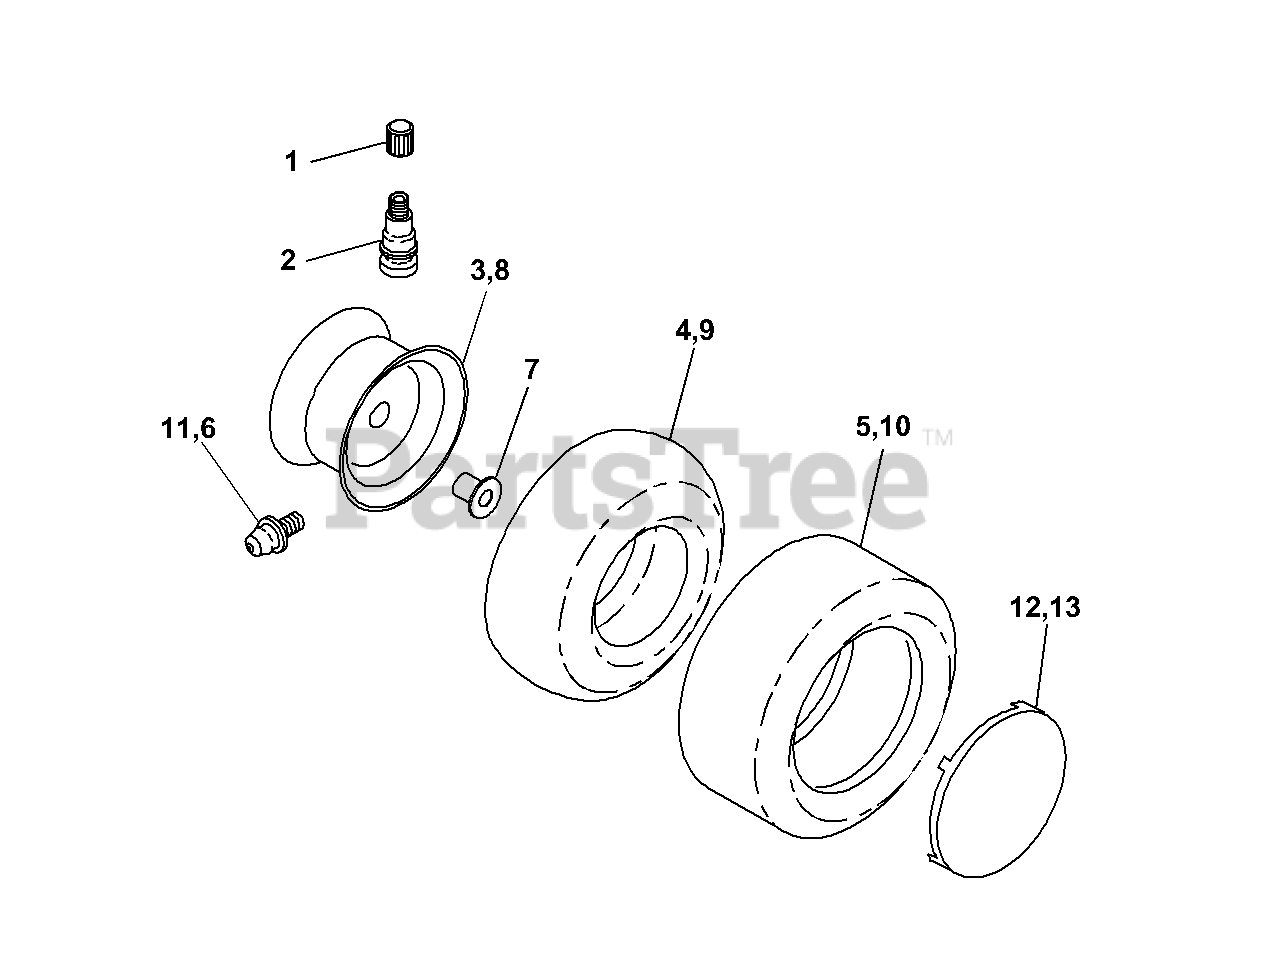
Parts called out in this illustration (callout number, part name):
1	Cap, Valve, Tire
2	Stem, Valve
3	Rim Assembly, Front
4	Tube, Front
5	Tire, Front
6	Fitting, Grease
7	Bearing, Flange
8	Rim Assembly, Rear
9	Tube, Rear
10	Tire, Rear
11	Fitting, Grease
12	Cover Wheel 8" White
13	Cover, Wheel 12" White
